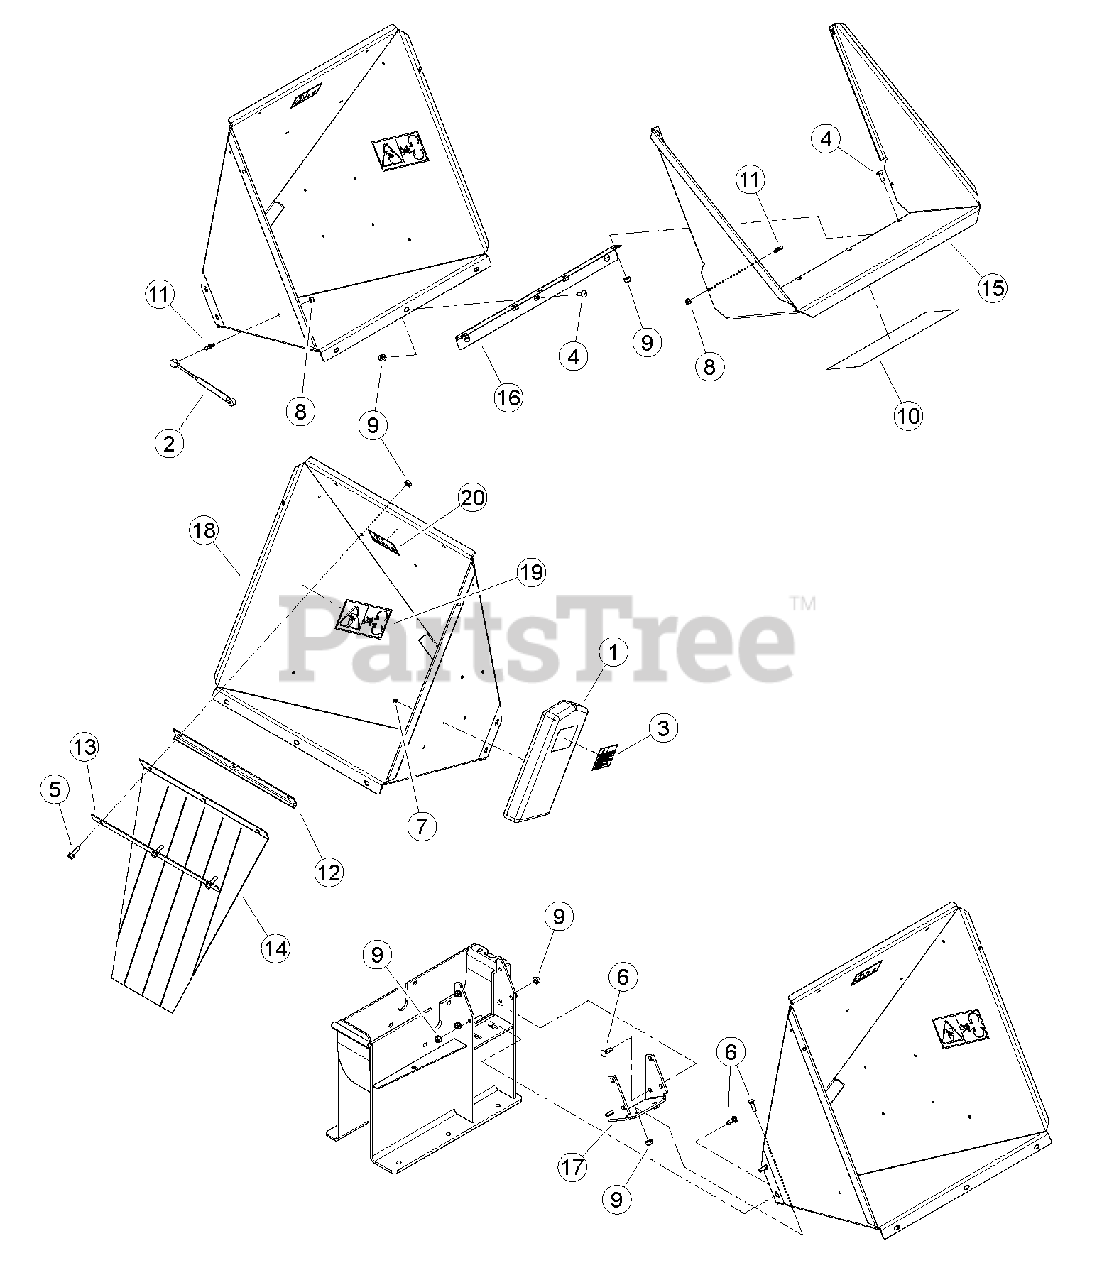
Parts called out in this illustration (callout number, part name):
1	CONTAINER, INSTR. MANUAL
2	SPRING, GAS 60 PSI
3	DECAL, MULTILINGUAL MANUAL
4	BOLT, 3/8-16 X 1 GR5 CRG
5	BOLT, 3/8 X 1-1/4 FLANGE NC
6	BOLT, 3/8-16 X 1-1/4 GR5 CRG
7	RIVET, 1/4 X 1/2 DOME HD BLIND SS
8	NUT, 5/16-18 NYLOCK FLANGE
9	NUT, 3/8-16 NYLOCK FLANGE
10	DECAL, BEARCAT WEB
11	BALL, .39 DIA STUD
12	ANGLE, FLAP ANCHOR
13	STRIP, FLAP RETAINER
14	FLAP, CHIPPER CHUTE
15	HINGE, EXTENSION TRAY
16	WELDMENT, EURO 5 IN CHUTE TRAY
17	BRACKET, CHUTE MOUNT
18	ASSEMBLY, 5" CHUTE WITH DECALS
19	DECAL, BLADE DANGER ISO
20	DECAL, MAINTENANCE ISO
